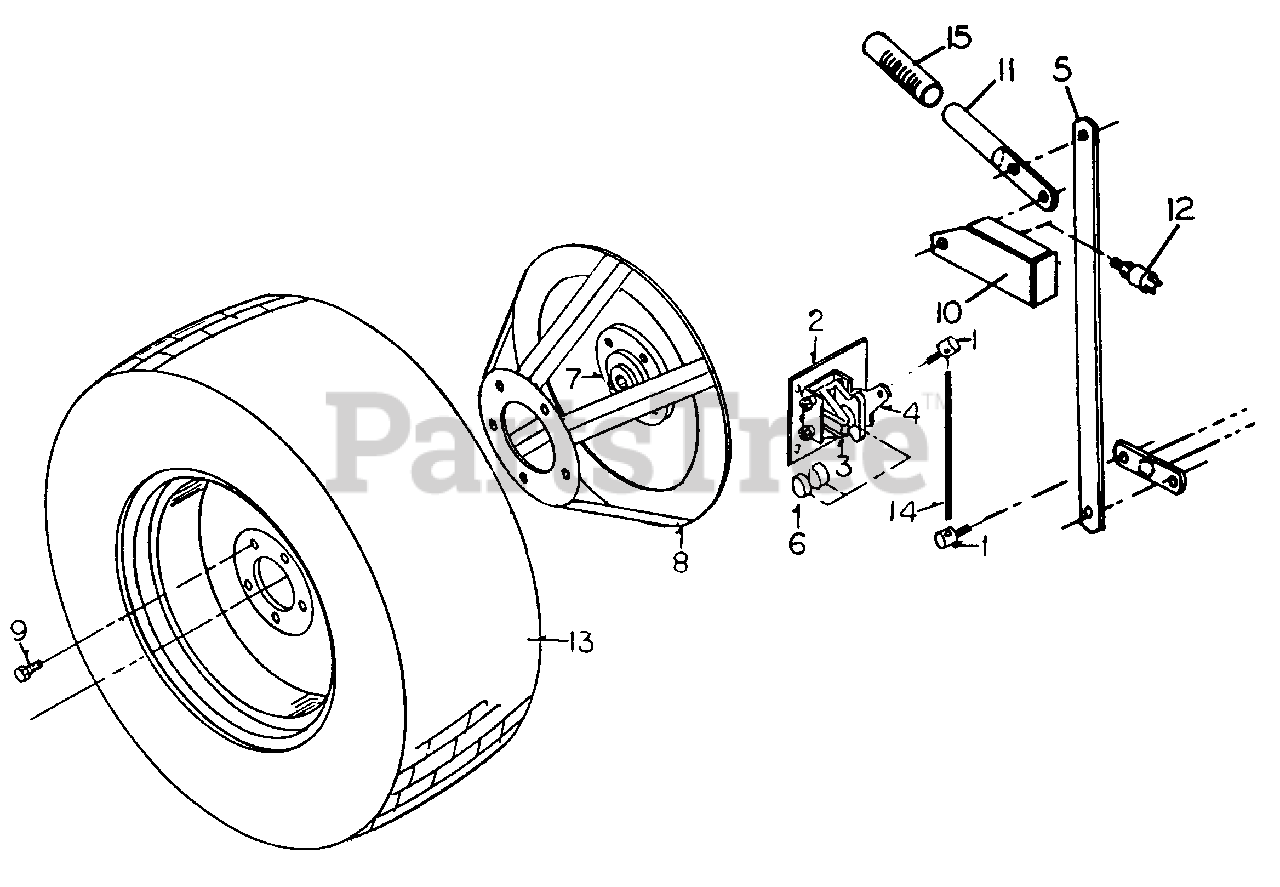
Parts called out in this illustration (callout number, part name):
1	Caliper Rod Collar
2	Brake Caliper Bracket
3	Brake Caliper
4	Caliper Lever, LH
5	Brake Lever Linkage
6	Brake Puck
7	5-Bolt Wheel Hub
9	Lug Bolt, 7/16-20 x 3/4"
10	Park Brake Mount
11	Park Brake Lever
12	Switch
13	Wheel Ass'y., 23 x lO.50-12
14	Brake Caliper Linkage Bolt
15	Handle Grip
